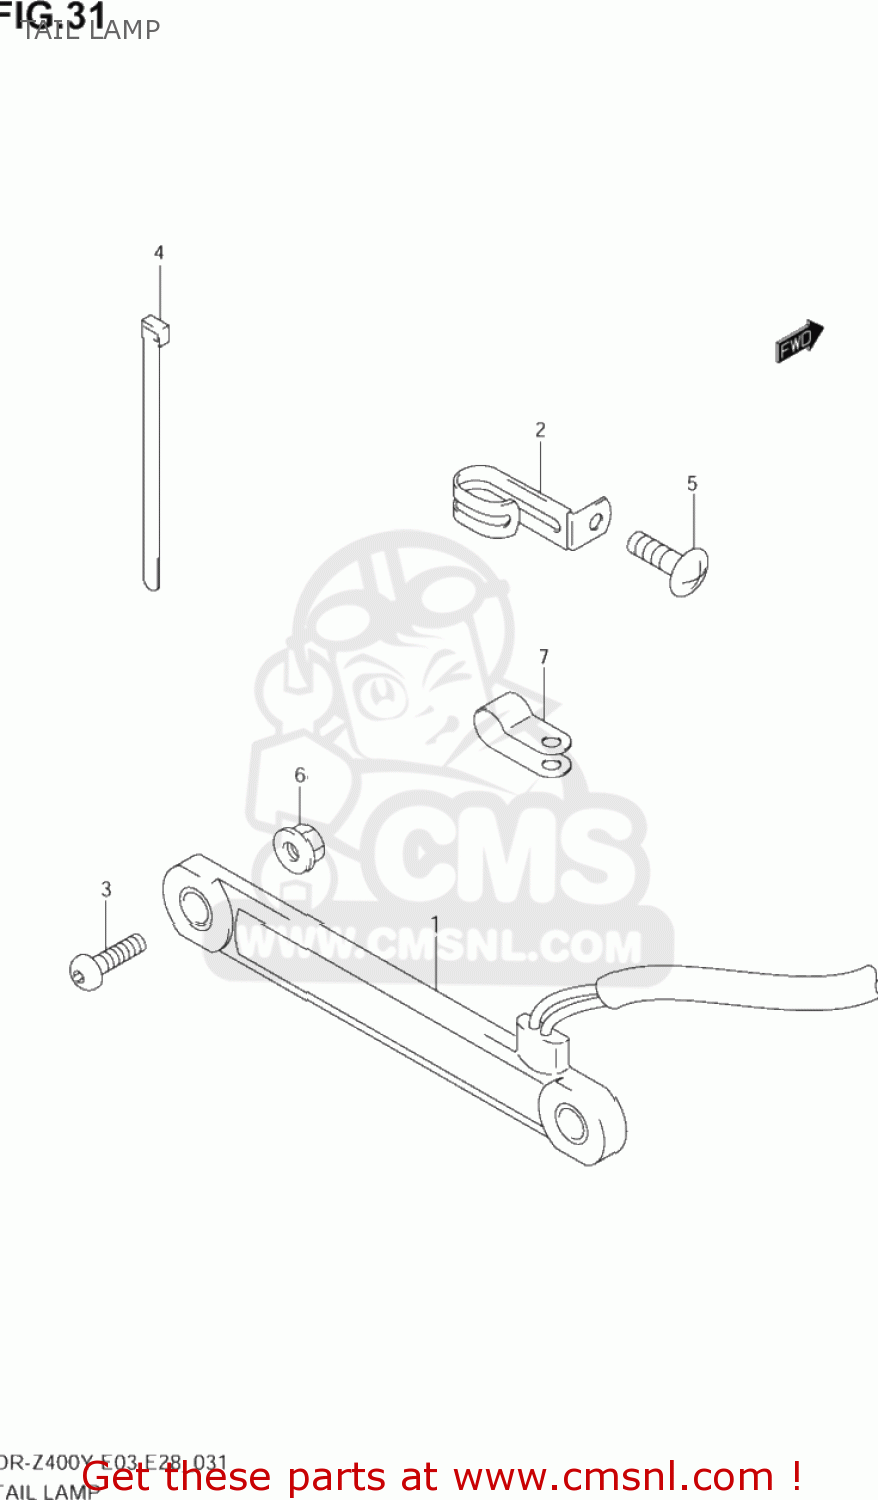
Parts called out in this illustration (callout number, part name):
1	LAMP ASSY,TAIL
2	CLAMP,TAIL LAMP LEAD
3	SCREW(5X18)
4	CLAMP(L:145)
5	SCREW
6	NUT
7	CLAMP
